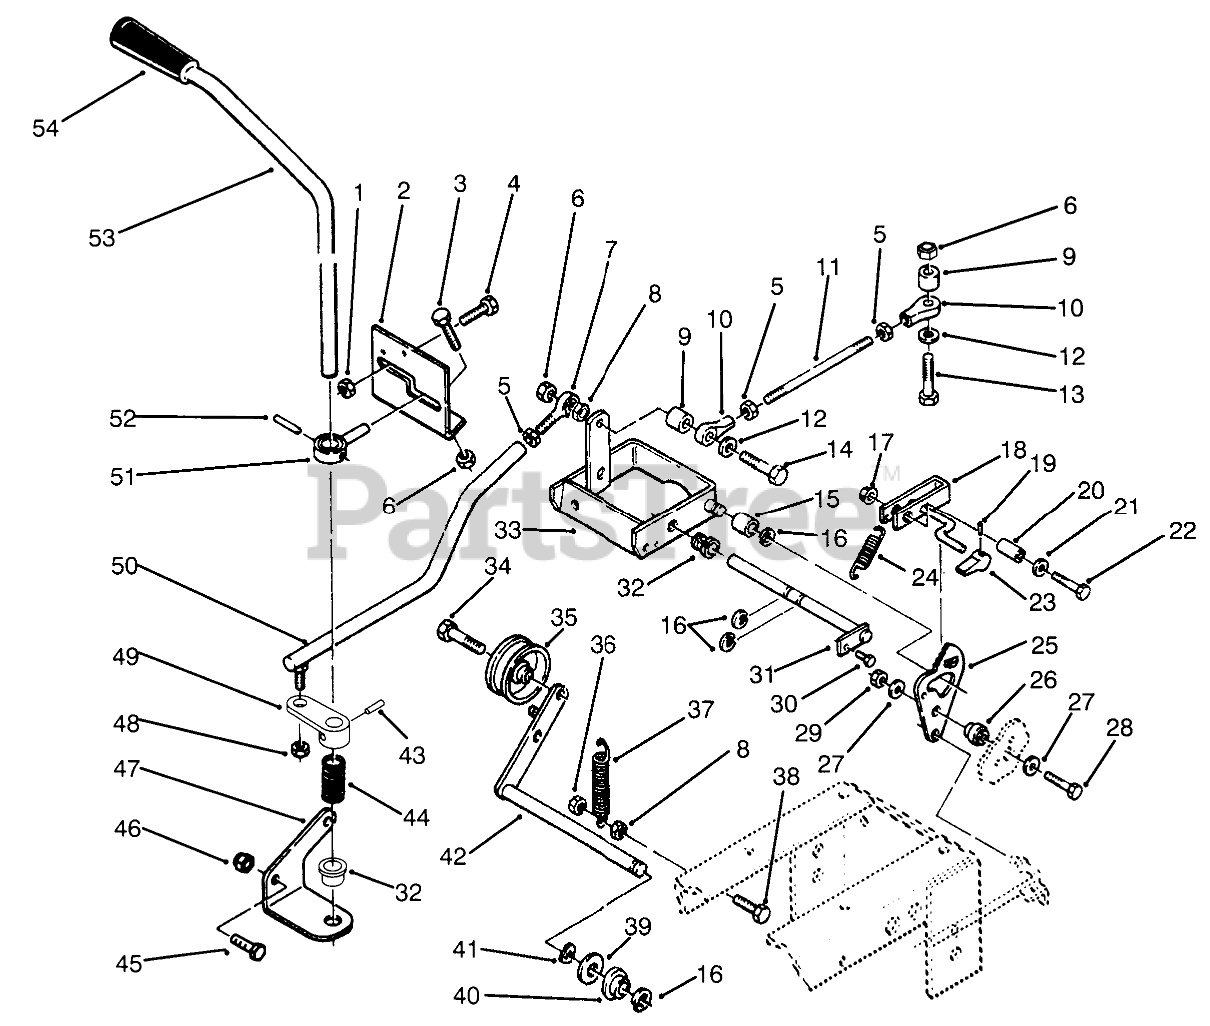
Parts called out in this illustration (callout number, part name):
1	NUT-LOCK, NI
2	BRKT-CONTROL
3	SCREW-HH
4	SCREW-HH
5	NUT-JAM
6	NUT-LOCK, NI
7	ROD END, 1/4-28
8	NUT-HEX
9	Spacer
10	ASSY ROD END
11	ROD-CONTROL
12	WASHER-FLAT
13	SCREW-HH
15	BEARING-CAM RETURN
16	RING-RETAINING, EXTERNAL
17	LOCKNUT-FLANGE
18	Lever-Parking Brake
19	PIN-SPIROL 3/32X5/8
20	SPACER
21	Washer
22	SCREW-HH
23	KNOB-PARKING BRAKE
24	EXTENSION-SPRING
25	Cam Plate
26	Spacer
27	WASHER-FLAT
28	SCREW-HH
29	NUT-LOCK, NI
30	SCREW
31	ASSY-ROD CAM PIVOT
32	NYLINER BUSHING
33	Cam Comtrol
34	SCREW-HH
35	PULLEY-IDLER
36	NUT-LOCK
37	SPRING-EXTENSION
38	SCREW-HH
39	Washer
40	BUSHING-FLANGED
41	CURVED-SPRING WASHER
42	WLDMT-IDLER ARM
43	PIN-SPECIAL
44	SPRING-COMPRESSION
45	SCREW-HH
46	NUT-LOCK, NI
47	Bracket-Control
48	NUT-LOCK
49	ARM-CONTROL
50	ASSY-ROD & BALL JOINT
51	GUIDE-CONTROL
52	SPIROL PIN 7/32X7/8
53	ROD-MOTION CONTROL
54	Knob-Motion Control
